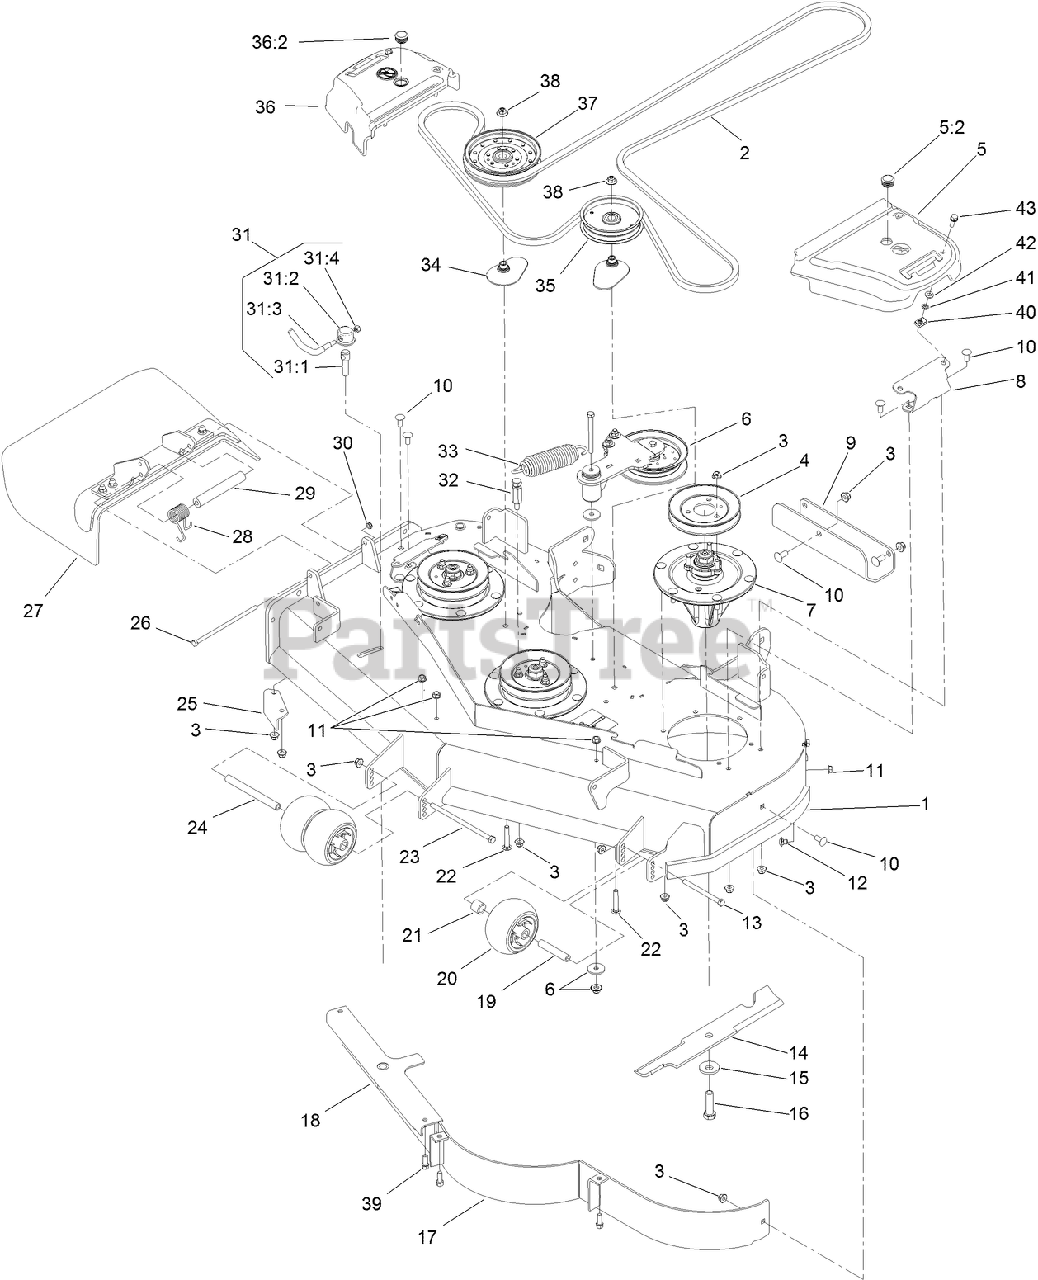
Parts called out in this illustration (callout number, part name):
1	DECK ASM
2	BELT-V
3	NUT-HF, NI
4	PULLEY
5	LH BELT COVER ASM
5:2	PLUG-PLASTIC
6	IDLER ARM ASM
7	SPINDLE ASM
8	BRACKET-COVER, BELT
9	PLATE-SKID
10	SCREW-CARR
11	NUT-HHF, WHIZ
12	SCREW-CARR
13	SCREW-HH
14	BLADE-16.5 INCH (HIGH FLOW)
15	Washer-Blade Bolt, Heavy
16	SCREW-BLADE
18	BAFFLE
19	TUBE-SPANNER
20	ROLLER-SCALP, ANTI
21	TUBE-SPACER
22	BOLT-CARR, SHORT NECK
23	SCREW-HH
24	SPACER-WHEEL
25	BAFFLE-DISCHARGE
26	SCREW-HH
27	RUBBER DEFLECTOR ASM
28	SPRING-TORSION
29	SPACER
30	NUT-LOCK, NI
31	LEVER ASM
31:1	Screw-Lock
31:2	CAP-LOCK
31:3	Lever-Lock
31:4	NUT-LOCK, NI
32	ANCHOR-SPRING, TALL
33	SPRING-EXTENSION
34	SPACER-PULLEY
35	PULLEY-IDLER, FLAT
36	RH BELT COVER ASM
36:2	PLUG-PLASTIC
37	PULLEY-IDLER, FLAT
38	NUT-FLANGE, NI
39	SCREW-HWH
40	NUT-U
41	NUT-PUSH
42	WASHER-THRUST
43	SCREW-HHF
